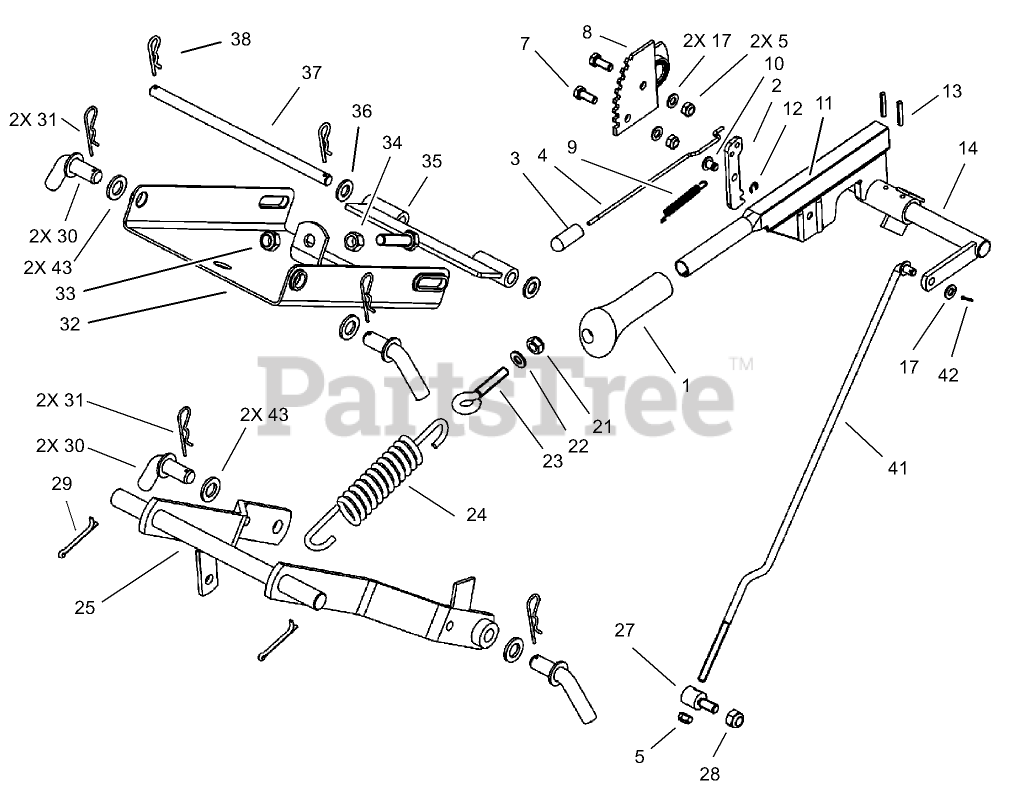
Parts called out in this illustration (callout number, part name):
1	GRIP-HANDLE
2	RATCHET-PLATE, PIVOT
3	BUTTON-PLUNGER
4	ROD-CONNECTION
5	NUT-LOCK, NI
7	SCREW-HH
8	SEGMENT-GEAR
9	SPRING
10	PIN-LEVER, ARM
11	LEVER-ARM, HEIGHT ADJ.
12	CLIP-PIN
13	PIN-SPRING
14	SHAFT-HEIGHT ADJ.
17	WASHER-PLAIN
21	NUT-LOCK, NI
22	WASHER-FLAT
23	BOLT-EYE
24	SPRING-LIFT
25	PIVOT ARM ASM
27	PIN-LIFTING
28	NUT-LOCK, NI
29	PIN-COTTER
30	PIN-BENT
31	PIN-HAIR
32	SUSPENSION-MOWER DECK, FRONT
33	NUT-HEX
34	NUT-HEX
35	HOLDER-FRONT
36	WASHER-FLAT
38	PIN-HAIR
41	ROD-HEIGHT, ADJ.
42	PIN-COTTER
43	Washer-Hose
